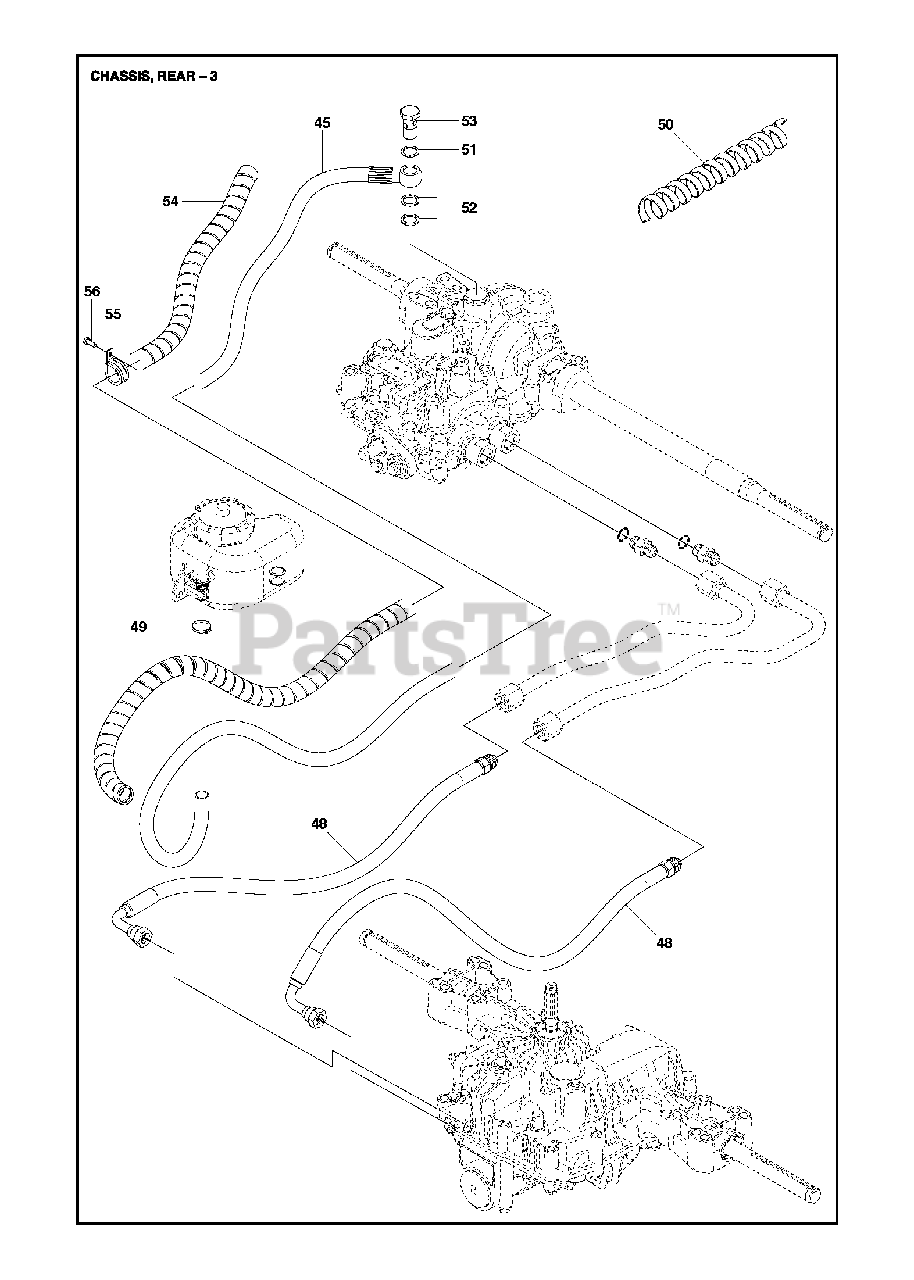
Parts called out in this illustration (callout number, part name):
45	HYDRAULIC HOSE
48	HYDRAULIC HOSE
49	HOSE CLIP
50	PROTECTOR
53	PIPE FITTING
54	HOSE GUARD
55	HOSE CLAMP
